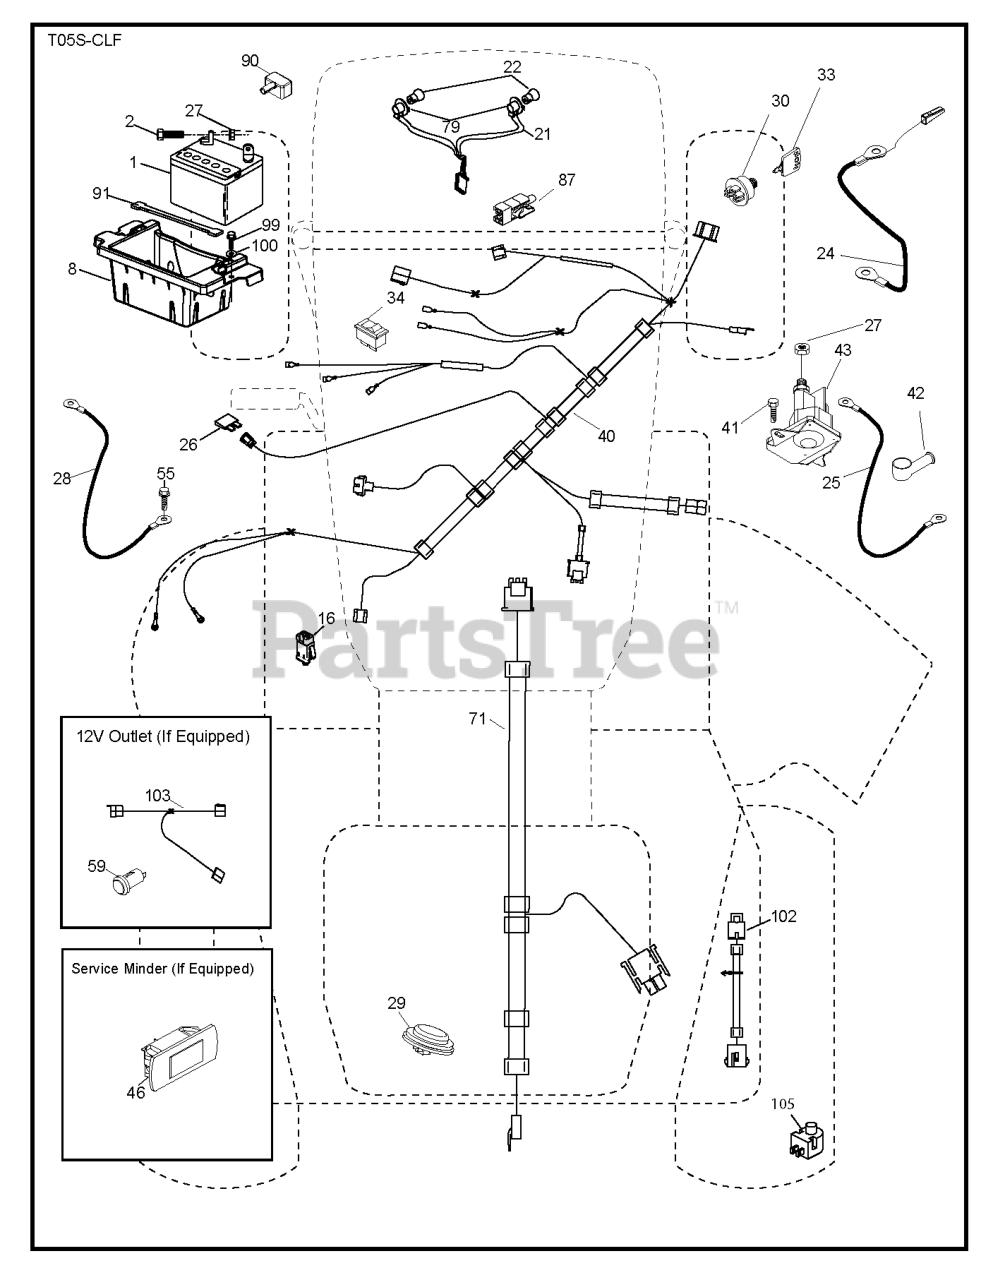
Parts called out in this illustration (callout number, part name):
1	Battery, Dry 30 Amp
2	BOLT.HEX.1/4.X.3/4.DICHROMATE
8	TRAY.ASM.BATTERY.FRT.TEX.CARB
16	SWITCH INTERLOOK PUSH-IN
21	HARNESS.LIGHT W/4152J BULBS
24	CABLE.BATT.POS.WIRE.TG.DA SOL
25	CABLE.STARTER.8GA.17.5
26	FUSE 20AMP
27	NUT
28	CABLE GROUND 6 GA 21" 90T BLK
29	SWITCH.SEAT.DELTA.OPC.
30	SWITCH.IGN.DELTA.W.LGH.ROS
33	KEY.CHAIN.BLISTER.PACK.GEN.USA
40	HARNESS IGN. DASH
41	SCREW
42	TERMINAL COVER
43	SOLENOID.W/BRASS.PLUNGER
46	RP.GUAGE.SRVCMNDR.HRMTR.
55	SCREW 5/16"
71	HARNESS-CHASSIS SUB
79	BULB HOLDER ASM.
87	SWITCH.INTRLCK.CLUTCH.
90	COVER.TERMINAL.BATTERY
91	STRAP.BATTERY.MOUNT.FRONT(2 2)
99	SCREW HEXWSHR 1/4-20X3/4
100	WASHER
102	HARNESS PIGTAIL PCH TEX ROS
105	REVERSE SWITCH
